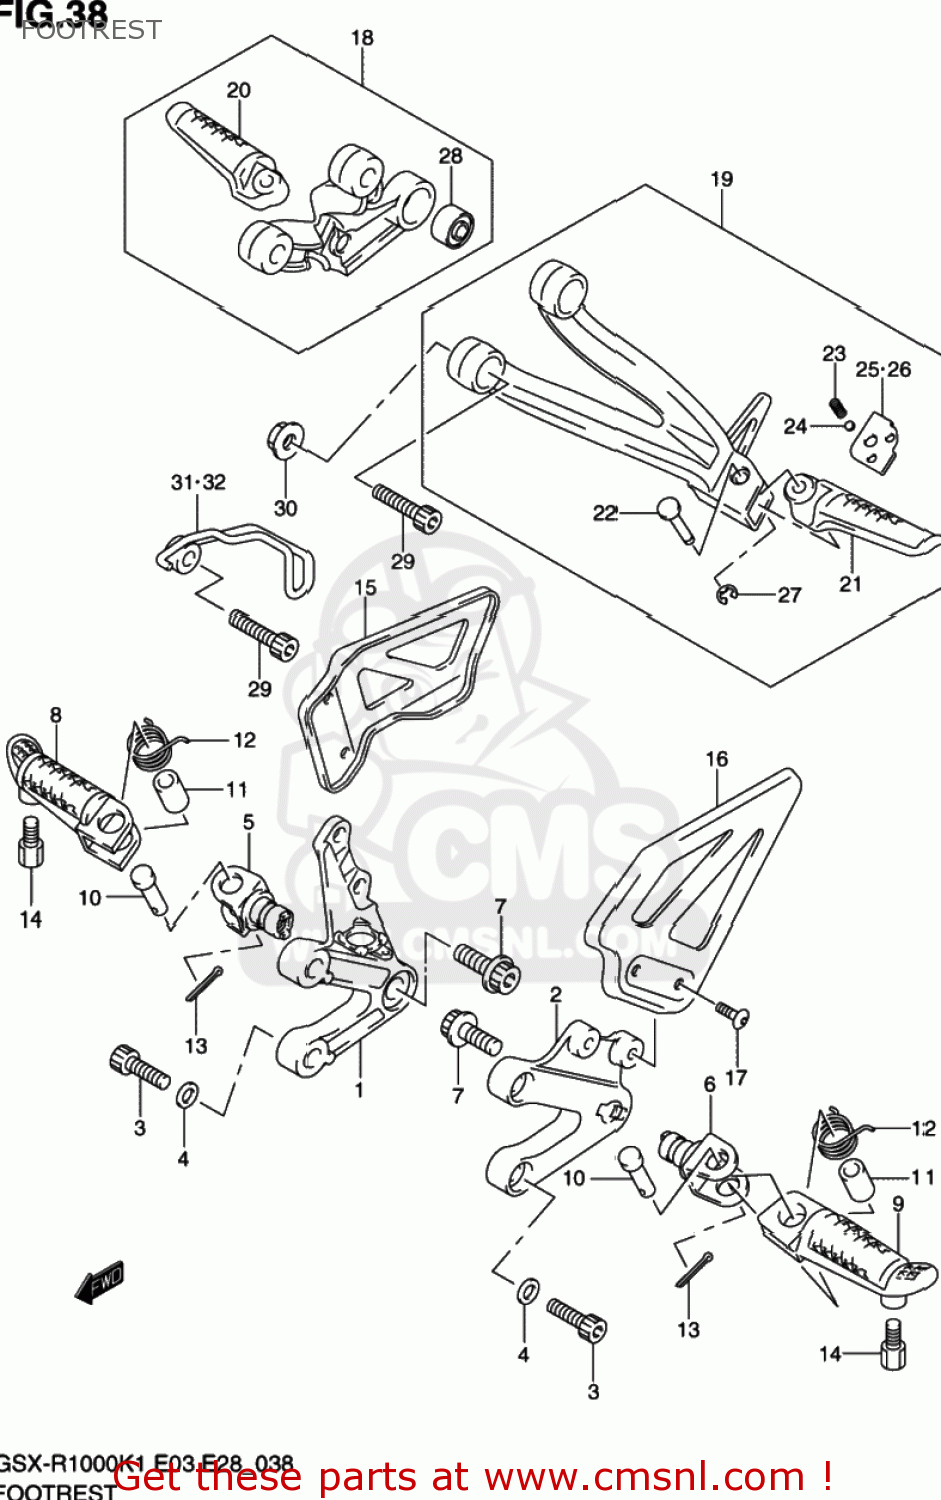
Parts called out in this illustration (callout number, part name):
1	BRACKET,FR FOOTREST,R
2	BRACKET,FR FOOTREST,L
3	BOLT,FOOTREST BRACKET
4	WASHER
5	HOLDER,FOOTRES
6	HOLDER,FOOTRES
7	BOLT(10X28)
8	BAR,FR FOOTREST,R
9	BAR,FR FOOTREST,L
10	PIN
11	SPACER(8.1X12X22)
12	SPRING
13	PIN 20X15
14	BOLT,BANK SENSOR
15	GUARD,FR FOOTREST,R
16	GUARD,FRONT FOOTREST,LEFT
17	SCREW(5X10)
18	FOOTREST ASSY,PILLION,R
19	FOOTREST ASSY,PILLION,L
20	BAR,PILLION FOOTREST,RIGHT
21	BAR,PILLION FOOTREST,LEFT
22	PIN
23	SPRING
24	BALL
25	PLATE,PILLION FOOT,R
26	PLATE,PILLION FOOT,L
27	E-RING
28	BUSH
29	BOLT
30	NUT
31	BRACKET,LUGGAGE HOOK,R
32	BRACKET,LUGGAGE HOOK,L
